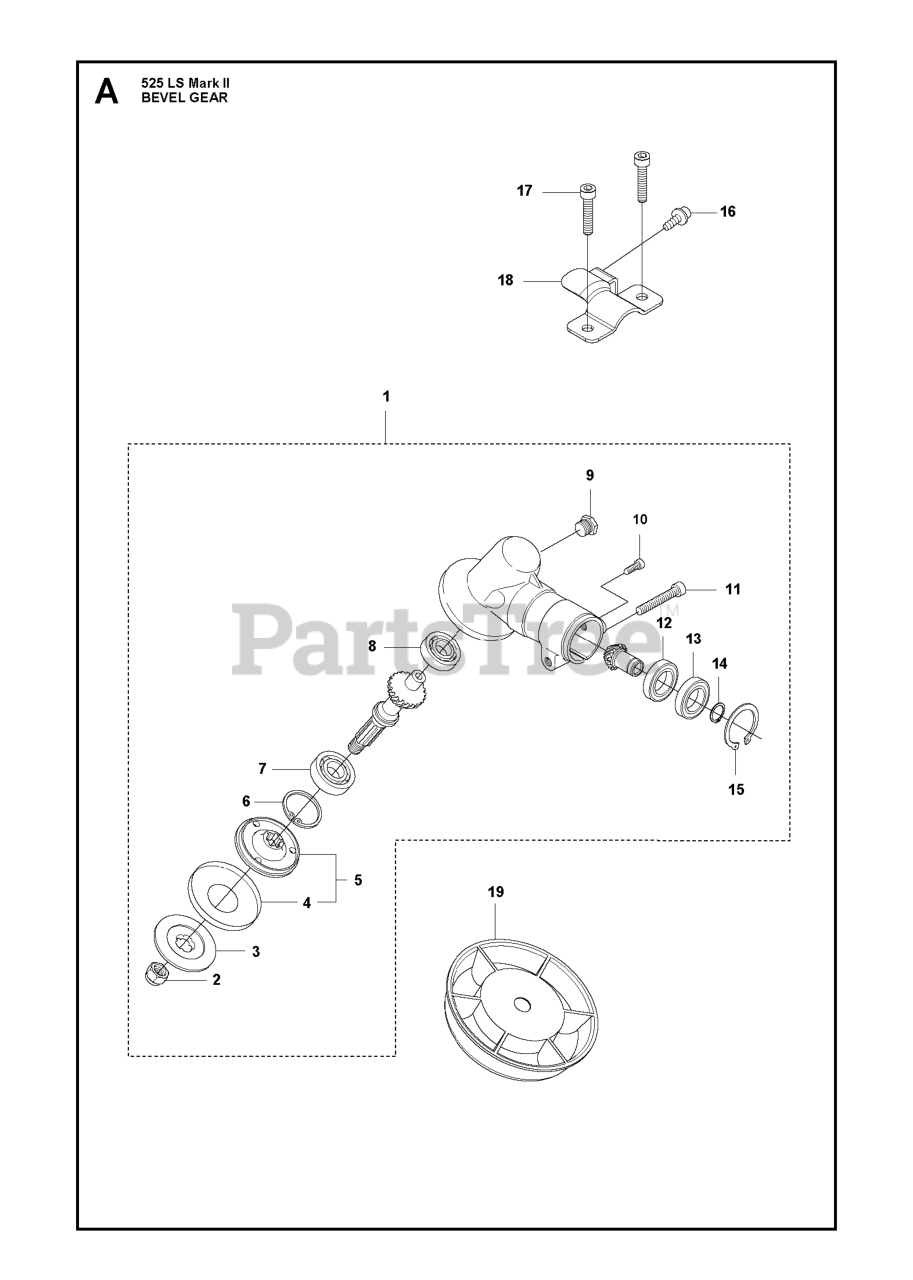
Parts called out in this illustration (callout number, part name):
1	GEAR HEAD
2	GEARHEAD NUT - BRUSHCUTTER
3	SUPPORT FLANGE
4	WASHER
5	DRIVE DISC
6	RETAINING RING SGH 28
7	BEARING
8	BALL BEARING 8X22X7/608Z
12	BALL BEARING 24X9X1/609ZR
14	RETAINING RING
15	RETAINING RING
17	BOLT, TORX
18	BRACKET SHIELD
19	SUPPORTING CUP
